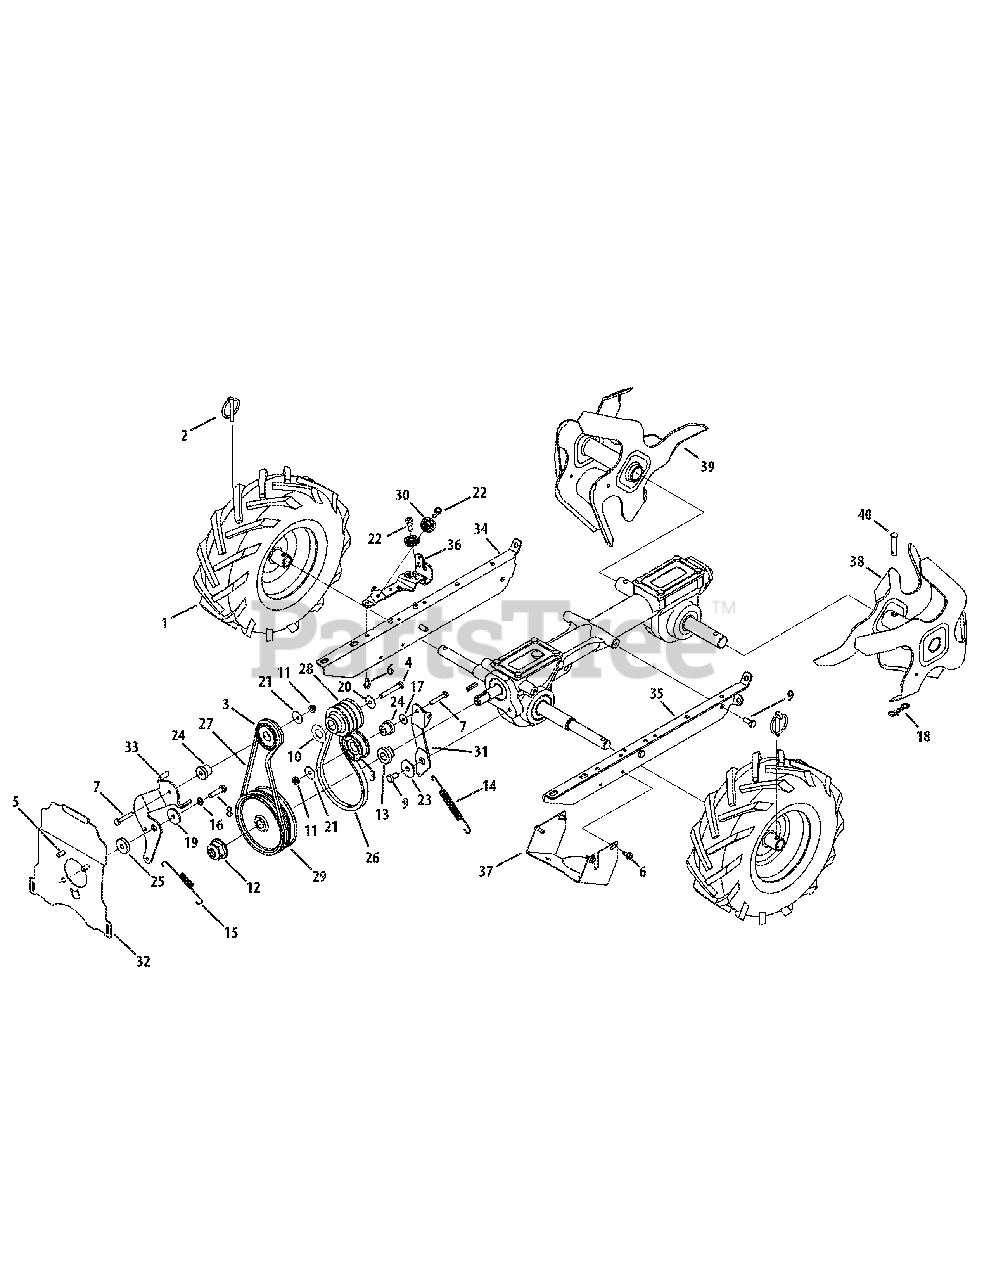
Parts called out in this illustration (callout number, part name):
1	Complete Whl. Ass., 13 x 5 x 6
2	Klik Pin
3	Idler Pulley Assembly
4	Hex Head Screw, 3/8-24 x 2.25
5	Hex Head Screw, 5/16-24 x .625
6	Self Tapping Screw, 1/4-20 x .500
7	Hex Head Screw, 1/4-20 x 1.50
8	Hex Head Screw, 5/16-18 x 1.25
9	Hex Head Screw, 5/16-18 x .75, Patch
10	Washer, Flat, .760 x 1.50 x .120
11	Nylon Hex Lock Nut, 1/4-20
12	Nut, 9/16-18, Flange Lock
13	Hub, 5/8 Spline
14	Extension Spring, .480 OD X 5.00 LG
15	Extension Spring, LT5 PTO
16	Lock Washer, 5/16
17	Washer, .28 x .74 x .063
18	Cotter Pin, Bow Tie
19	Flat Washer, .330 X 1.25 X .120
20	Bell Washer, .396 x 1.140 x .095
21	Flat Washer, .265 x 1.0 x .030
22	Shoulder Screw, .342 x .335 1/4-28
23	Pivot Idler Spacer
24	Shoulder Spacer, .260 x .785 x .538
25	Pivot Idler Spacer
26	V-Belt, 4L x 25.375 Long
27	V-Belt, 3L x 29.125 Long
28	Engine Pulley
29	Transmission Pulley
30	Cable Roller
31	Idler Bracket, Forward
32	Cover Plate
33	Idler Bracket, Reverse
34	Mounting Frame, RH
35	Mounting Frame, LH
36	Pulley Bracket
37	Pulley Shield
38	Tine Assembly, LH
39	Tine Assembly, RH
40	Clevis Pin, .375 x 1.75
